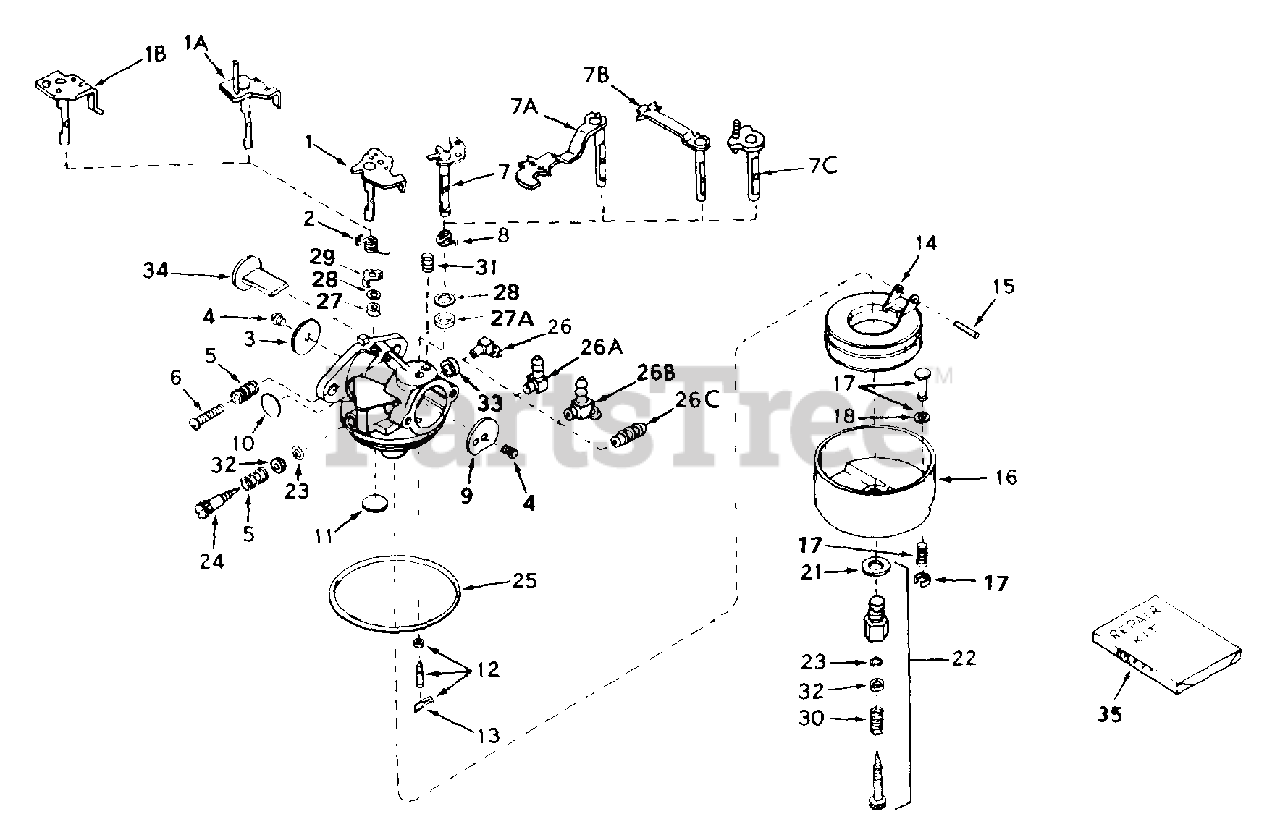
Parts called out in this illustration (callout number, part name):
1	"Shaft & Lever Assy, Throttle
2	Spring, Throttle return
3	Shutter, Throttle
4	Screw, Throttle & Choke, shutter
5	Spring, Regulating screw
6	Screw, Idle regulating
7B	Shaft & Lever Assy, Choke
9	Shutter, Choke
10	Plug, Welch
11	Plug, Welch
12	Inlet Needle, Seat & Clip Assy
13	Clip, Inlet needle
14	Float, Carburetor
15	Shaft, Float
16	Bowl & Drain Assy, Float
17	Plunger Assy, Drain
18	gasket, Drain plunger
21	Gasket, Bowl-to-body
22	Adj. Screw Assy, Main
23	"O" Ring, Adj. screw
24	Screw, Idle adj.
25	"O" Ring, Bowl-to-body
26C	Fitting, Fuel inlet
30	Spring, Main Adj. screw
31	Spring, Choke positioning
35	Repair Kit
